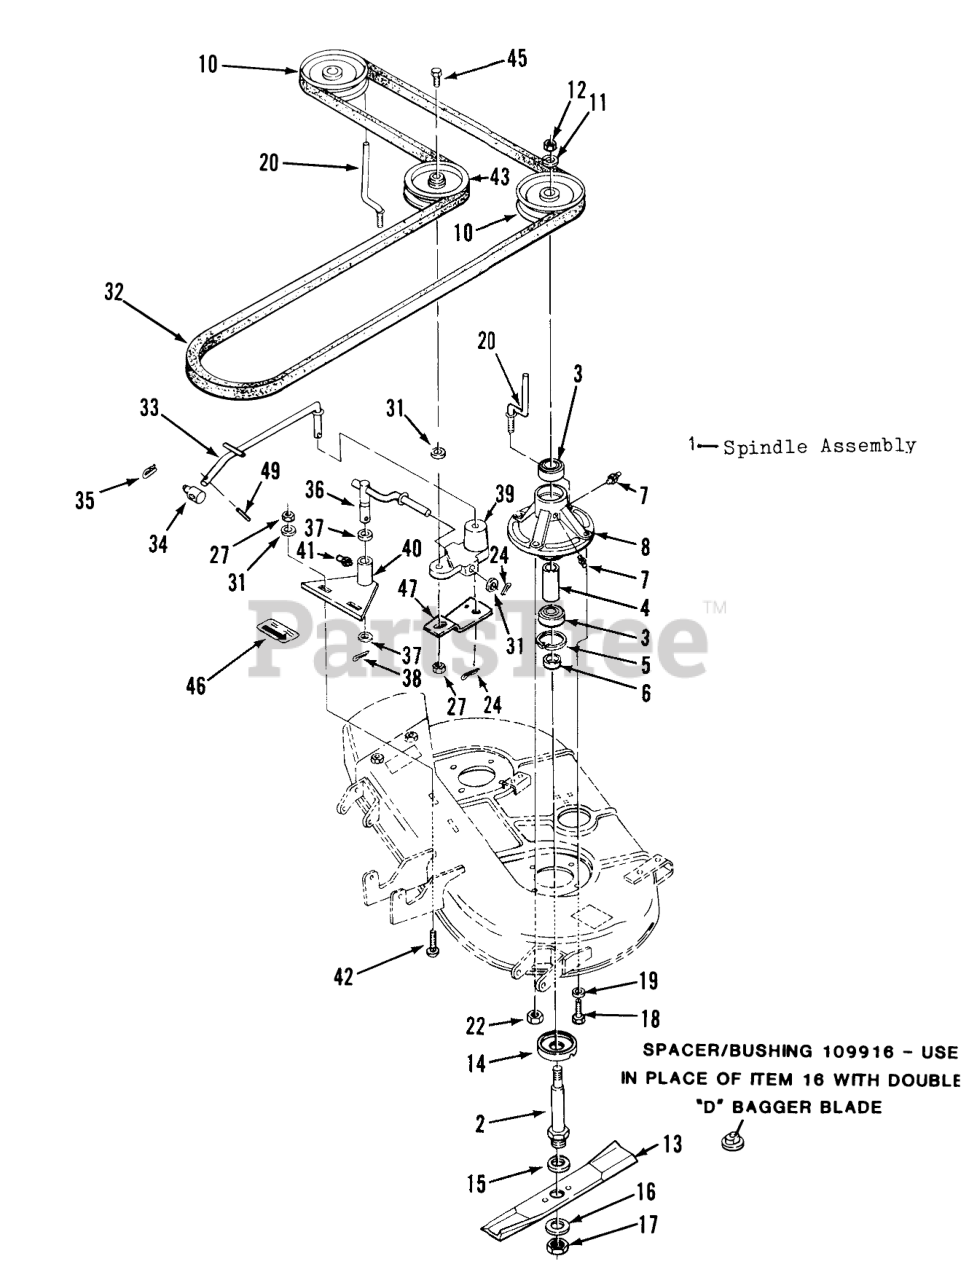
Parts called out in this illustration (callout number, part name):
1	Spindle Assembly (Includes items 2 thru 8 & 14)
2	SHAFT SPINDLE
3	BEARING-BALL
5	Ring-Snap
6	SPACER-BLADE
7	Fitting-Grease
8	HOUSING-SPINDLE
10	PULLEY-BLADE
11	Lockwasher
12	Jam Nut
13	ASSY BLADE KIT
14	CUP-SPINDLE
15	Washer
16	Washer
17	Nut-Jam
18	BOLT
19	LOCKWASHER
20	ROD-GUIDE
22	NUT
24	Pop Rivet
27	NUT
31	Washer
32	Drive Belt
33	ASS'Y-ROD IDLER B
34	TRUNNION-LIFT
35	Hairpin Cotter
36	ARM ASSEMBLY R
37	WASHER
38	Cotter Pin
39	BLOCK IDLER
40	IDLER BRACKET ASS R
41	FITTING-GREASE
42	Bolt
43	PULLEY-FLAT IDLER
45	Bolt
46	DECAL-BELT ADJUST
47	ANCHOR-SPRING B
49	Pin-Roll
